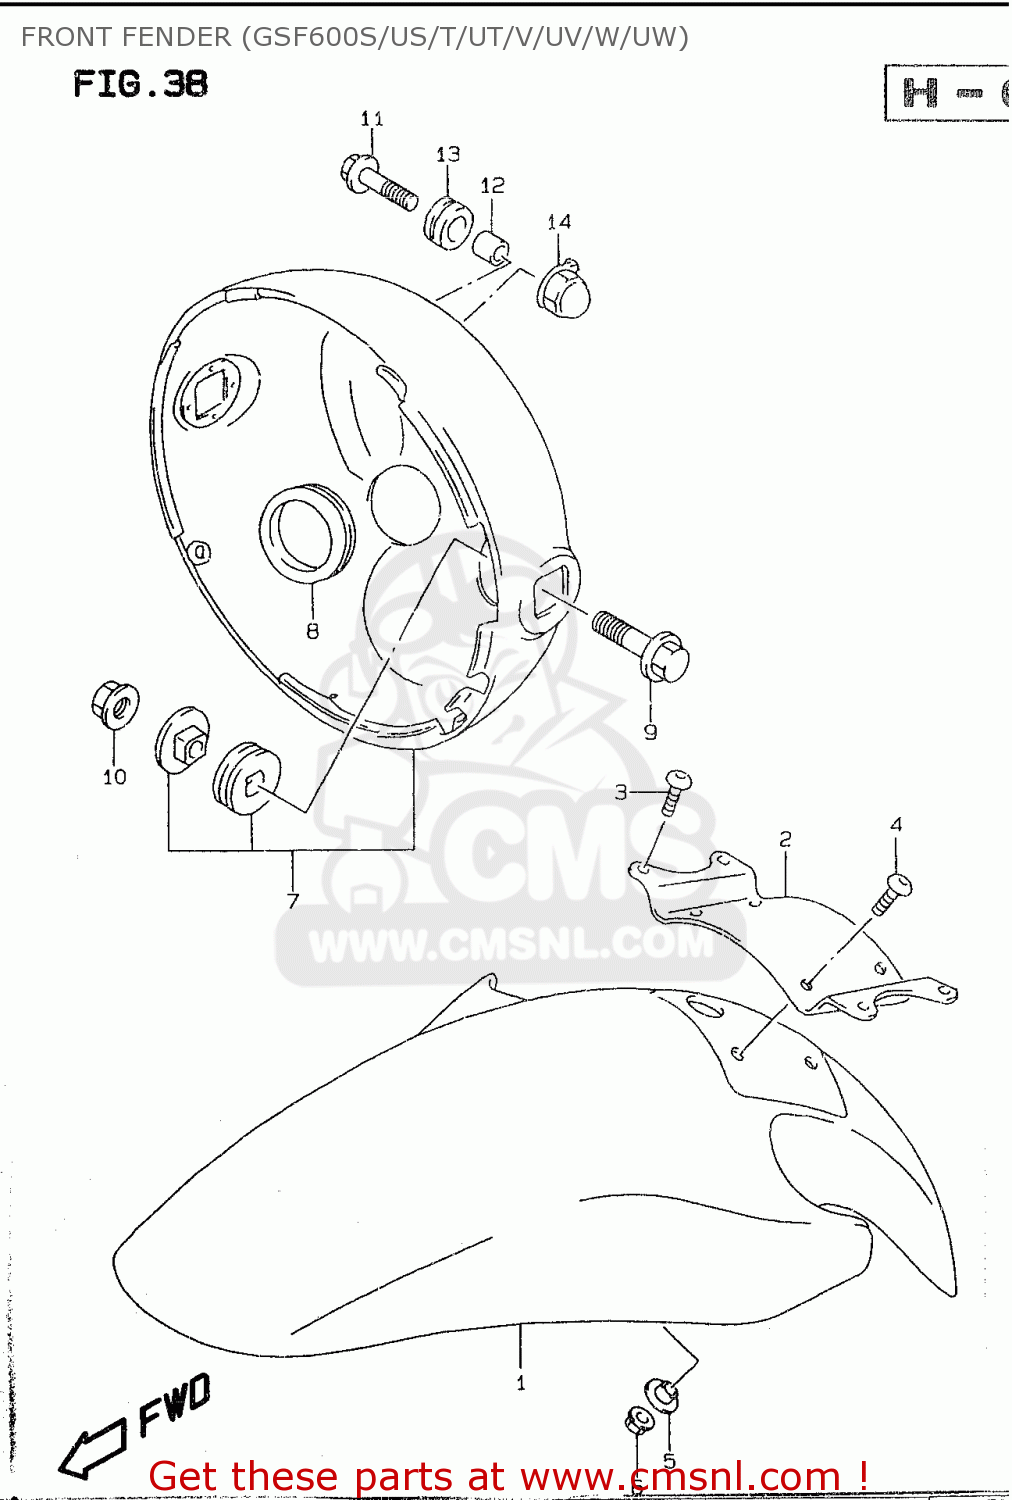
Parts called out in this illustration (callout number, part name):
1	FENDER SET,FR
2	BRACE,FR FENDER
3	SCREW(6X12)
4	SCREW(5X16)
5	WASHER
6	NUT
7	HOUSING,HEADLAMP
8	GROMMET
9	BOLT
10	NUT
11	BOLT
12	SPACER(6.5X10.5X12)
13	CUSHION
14	PLATE,HEADLAMP
